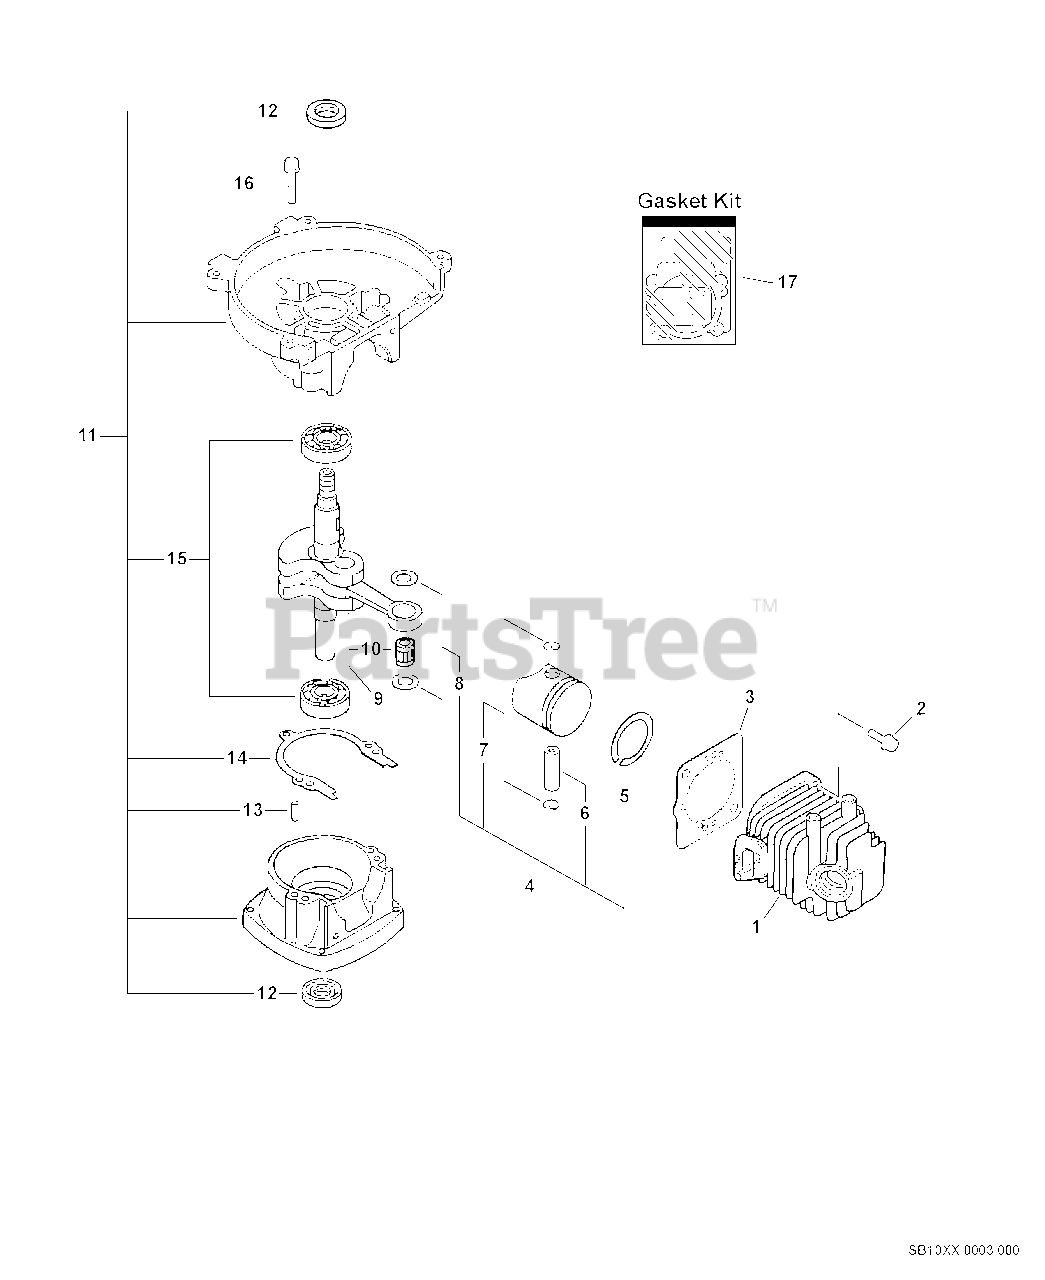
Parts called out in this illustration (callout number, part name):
1	CYLINDER
2	SCREW - 5X22
3	GASKET, CYLINDER
4	PISTON KIT
5	RING, PISTON
6	PIN, PISTON
7	RING, RETAINING
8	SPACER, PISTON
9	CRANKSHAFT ASSY
10	BEARING, NEEDLE - 8
11	CRANKCASE KIT
12	SEAL, OIL
13	PIN - LOCATING
14	GASKET, CRANKCASE
15	BEARING, BALL - 6201
16	SCREW - 5X28
17	GASKET KIT
